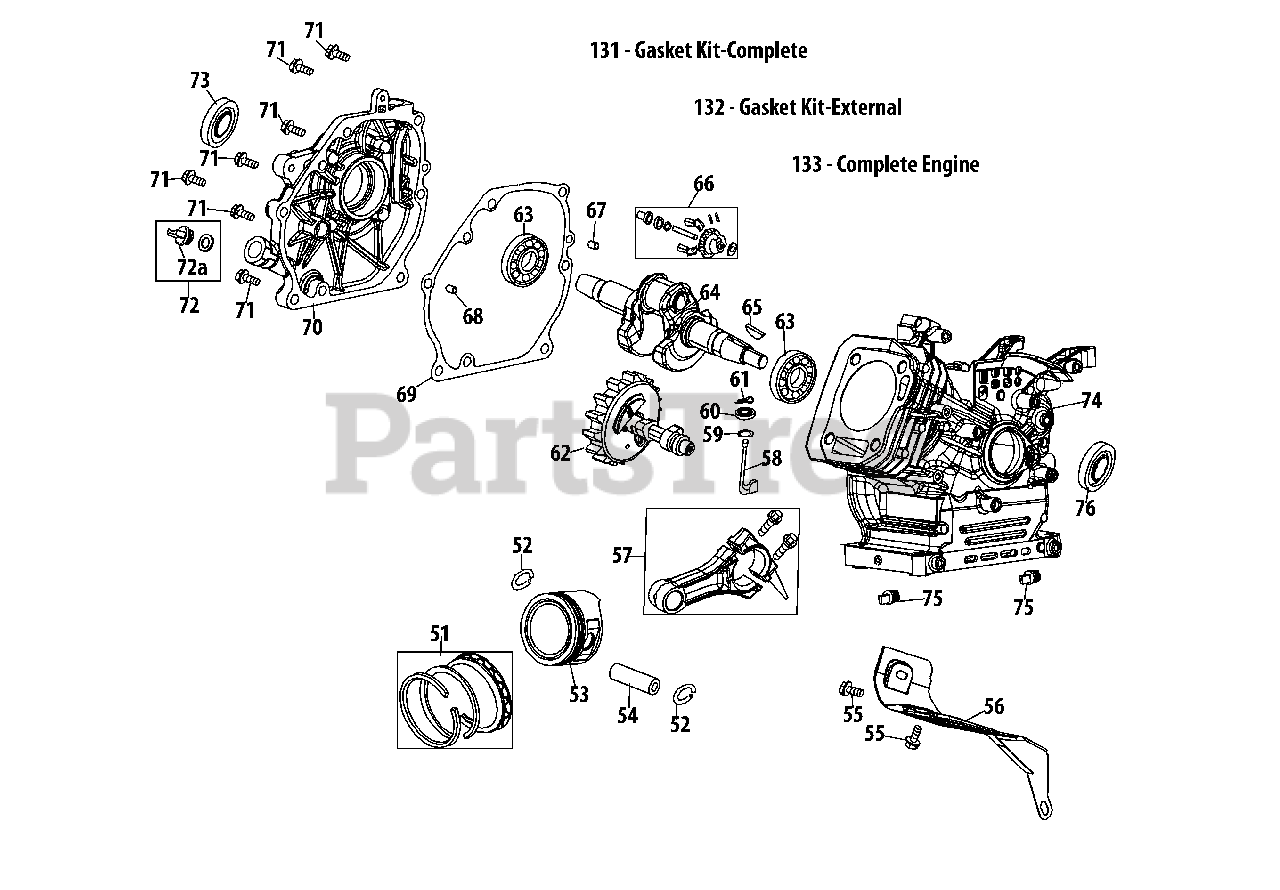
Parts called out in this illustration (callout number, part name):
51	Piston Ring Set
52	Piston Pin Snap Ring
54	Piston Pin
55	Bolt M6×12
56	Air Shield
57	Connecting Rod Assembly
58	Governor Arm Shaft
59	Washer 5.2×1.9
60	Governor Seal
61	Cotter Pin
62	Camshaft Assembly
63	Radial Ball Bearing,6205
64	Crankshaft Assembly
64	Crankshaft Service Kit
65	Woodruff Key
66	Governor Gear/Shaft Assembly
67	Dowel Pin 7×14
68	Dowel Pin 9×14
69	Crankcase Cover Gasket
70	Crankcase Cover
70	Crankcase Cover Kit
71	Bolt M8×32
72	Oil Fill Plug Assembly
73	Oil Seal,25×41.25×6
74	Crankcase Service Kit
74	Short Block Assembly
75	Oil Drain Plug
76	Oil Seal 25 X 41.25 X 6
131	Gasket Kit-Complete
132	Gasket Kit-External
133	Complete Engine
